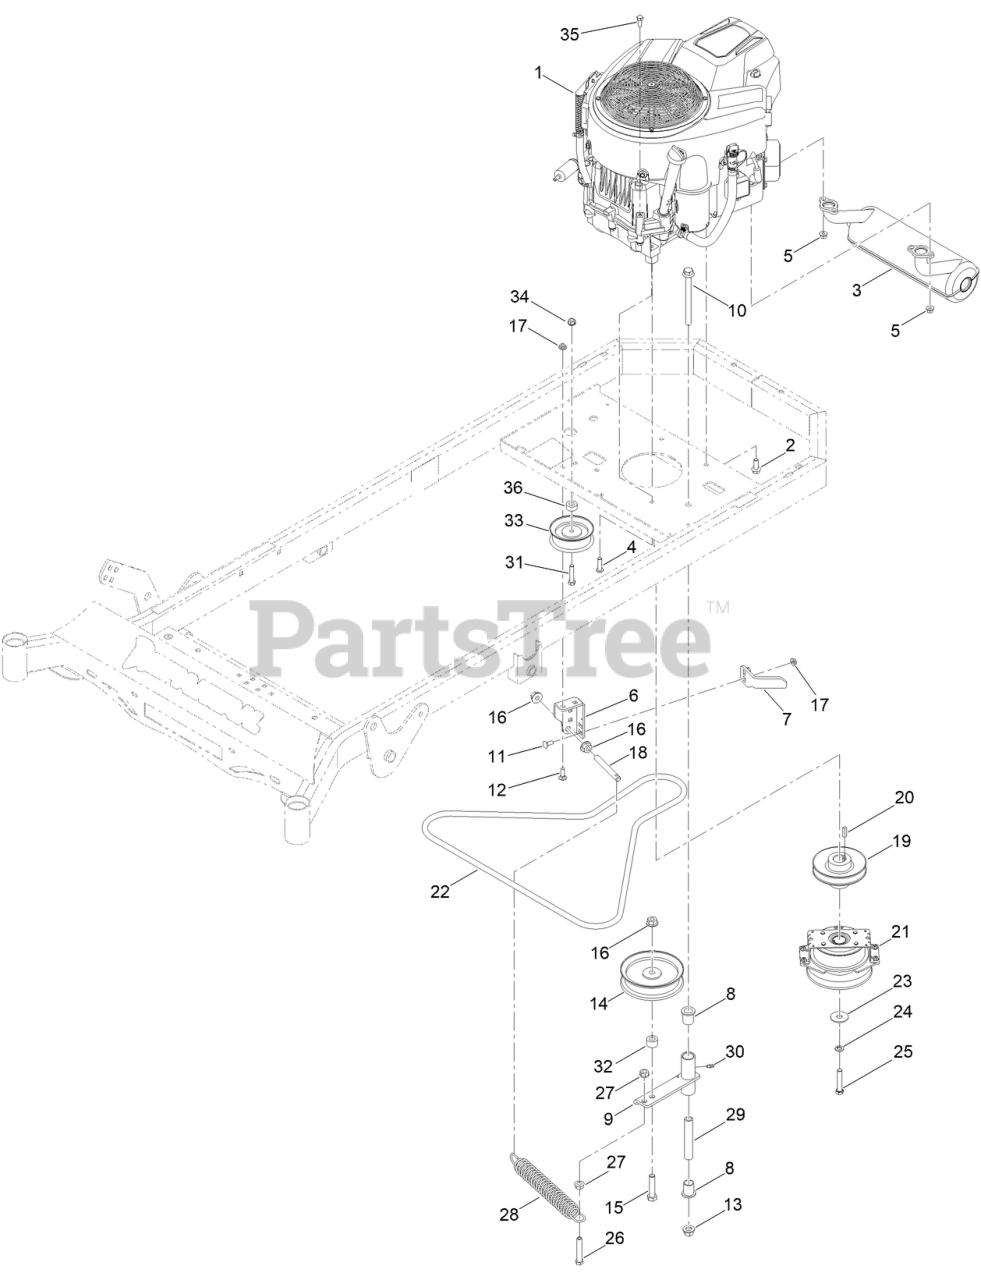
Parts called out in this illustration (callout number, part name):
1	25HP BRIGGS CXI ENGN
2	3/8-16 X 1-1/8 IND HWH W/SERR TRI LOB ZY
3	EXHAUST SYST BRIGGS 25/ 27HP ENGNS
4	3/8-16 X 1-1/4 PAN TORX (TRI-LOB) TRS ZC
5	NUT-HF
6	MWR PUMP IDLER TENSIONING BRKTPAINTED
7	2021 TTQ MWR OGURA CLUTCH BRKT PAINT
8	3/4IN ID X15/16IN OD X 1-1/8IN FLNG BUSH
9	MWR PUMP IDLER ASSY PAINTED
10	1/2-13 X 5-1/2 HEX FLANGE BOLT GR 8 ZY
11	BOLT-CARR
12	BOLT-CARR
13	NUT-LOCK
14	5-3/4IN IDLER PULLEY 7/16IN SPACER ASSY
15	1/2-13 X 3 HEX C/S GR 5 ZINC W/LOCTITE
16	NUT-HHF
17	NUT-HF
18	MWR PUMP IDLER SPRING TENSIONER
19	MWR HYDRAULIC PUMP DRIVE PULLEY (B-BELT)
21	MWR TTQ OGURA CLUTCH
22	MWR TTQ PUMP BELT
23	1/2IN X 1-5/8 BELLEVILLE CUP WASHER YZ
24	WASHER-LOCK
25	TTQ CLUTCH BOLT
27	NUT-HF
28	MWR DECK SPRING
29	MWR INNER IDLER SPACER
30	1/4IN DRIVE TYPE GREASE FITTING YZ
31	SCREW-HH
32	.530 ID/ 1IN OD X .625 PUMP IDLER SPACER
33	4IN DIESEL AND ECONOMY MWER IDLER PULLEY
34	NUT-HHF, WHIZ
35	M8-1.25 X 20MM HEX FLANGE BOLT ZINC 10.9
36	MWR PULLEY SPACER
